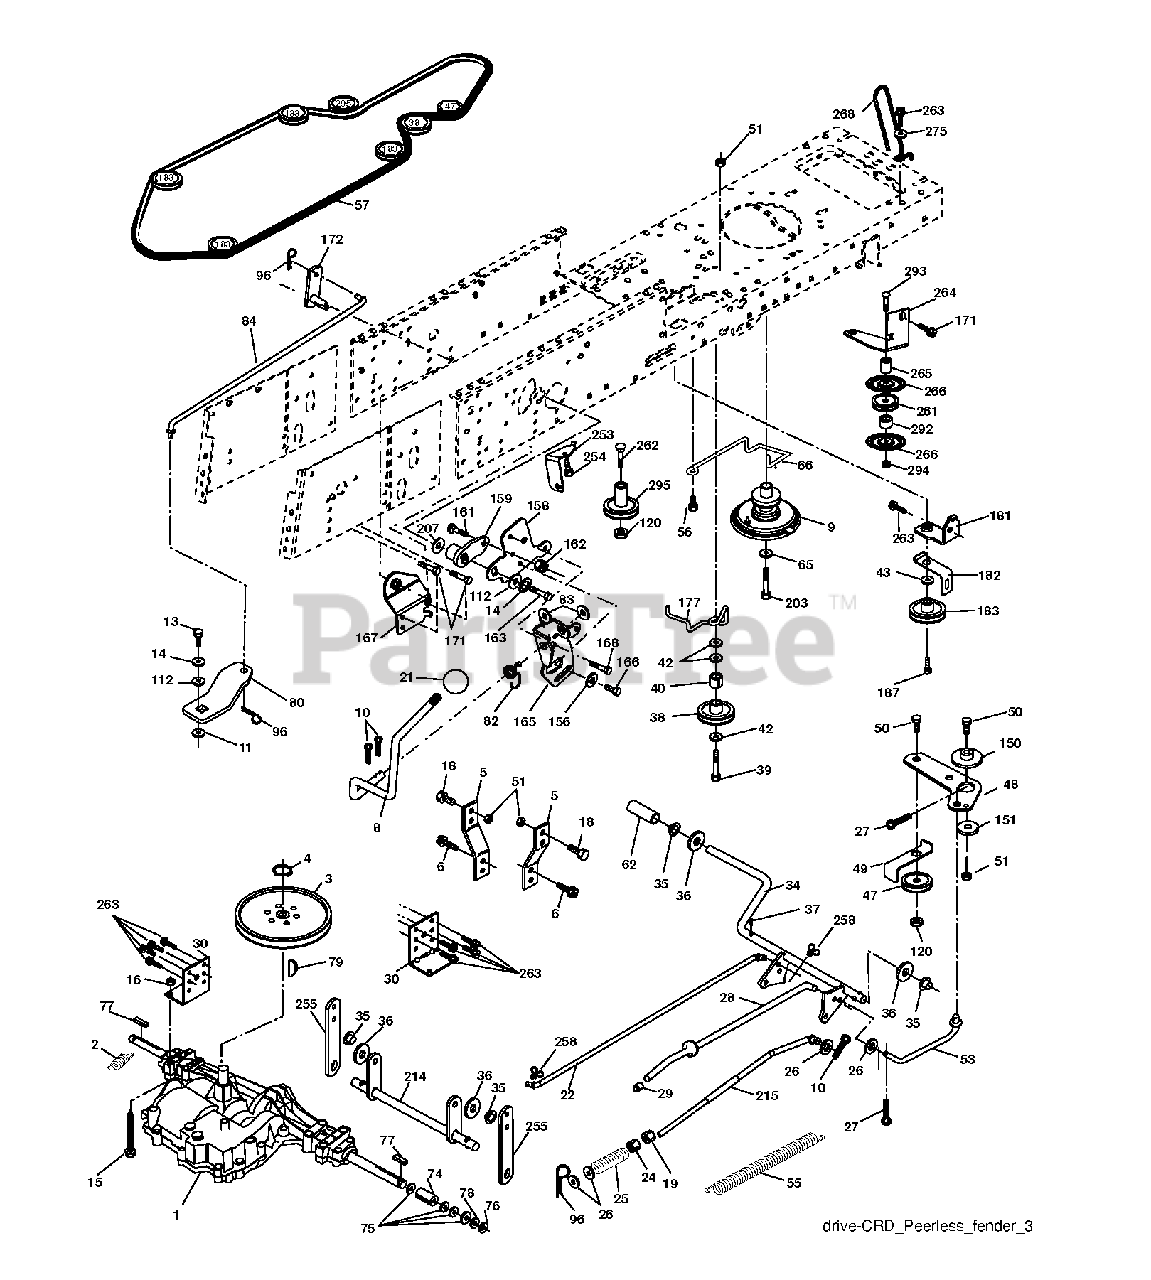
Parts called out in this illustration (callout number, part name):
2	SPRING,BRAKE RETURN
4	RETAINING RING LT
5	STRAP TORQUE
6	SCREW 5/16"
8	ROD SHIFT FENDER ADJUST LT
10	PIN COTTER
11	WASH-SHFT PLT LT
13	BOLT 1/4-28X3/4
14	LOCKWASHER
15	BOLT HEX 5/16-18 GR 5
16	NUT.71038.31-18.HEX.NYLOCK
19	NUT
21	KNOB.DUCKHEAD.1/2
24	NUT
25	SPRING ROD LT
27	COTTER PIN
28	ROD, PARKING BRAKE
29	PLUNGER CAP
30	BRKT, MOUNT TRNSAXLE
34	SHAFT, FOOT PEDAL
35	BEARING.NYLON
36	WASHER LT
37	DRIVE PIN
38	PULLEY.FLAT
42	WASHER
47	IDLER PULLEY
48	BELLCRANK, CLUTCH
49	RETAIN BELT
50	BOLT.3/8-16X1.50
51	LOCKNUT
53	LINK.CLUTCH.7.66.2005
55	SPRING, RETURN LT
56	SCREW.3/8-16
57	V-BELT.KEV.111"
62	PEDAL COVER T
65	LOCKWASHER
66	KEEPER BELT ENGINE
74	SPACER AXLE
76	E-RING LT
77	SQUARE KEY
80	ARM SHIFT
82	SHIFT SPRING
83	WASHER
96	RETAINER M
112	WASHER LT
120	NUT LOCK FLG 3/8-16 UNC
150	BUSHING.BELLCRANK.GRD.DR
151	WASHER 12/32X2X10GA
156	WASHER.SRRTD.5/16
158	BRACKET
159	HUB.SHIFT
161	BOLT
162	NUT.CROWNLOCK.1/4
165	RP BRACKET
167	BRACKET
168	BOLT.SHOULDER.5/16-18X
187	BOLT.5/16-18X1.25
207	WASHER NYL
254	SCREW 3/8-16X1
258	CLIP RETAINER
261	FLAT IDLER PULLEY
263	SCREW, 3/8-16X3/4
275	WASHER
294	NUT, HEX 3/8-16
295	PULLEY IDLER COMPOSITE
